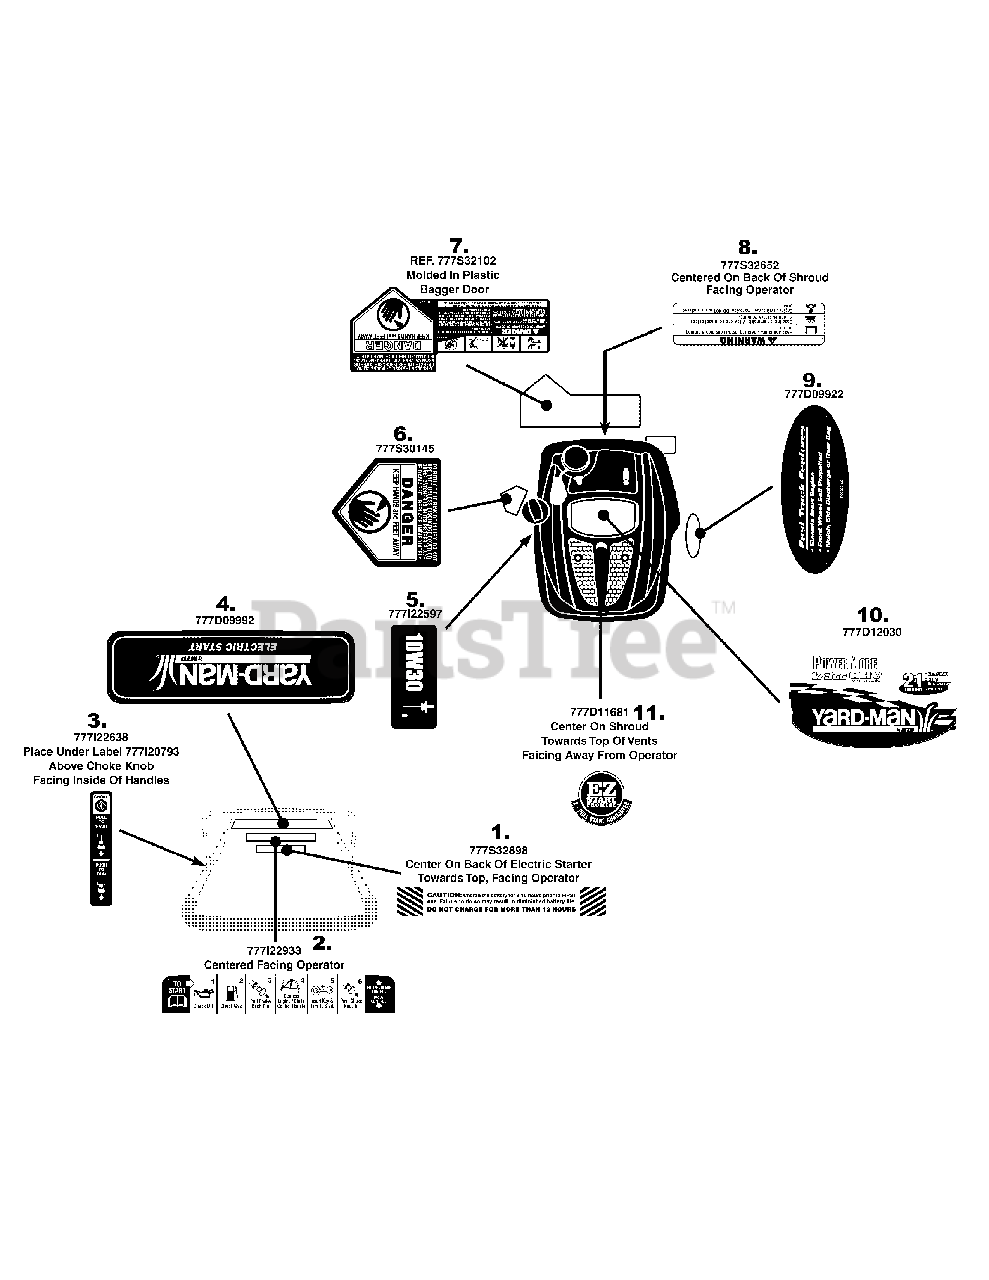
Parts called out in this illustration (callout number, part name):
1	LABEL-MOWER CHARGE CAUTION
2	LABEL-STRT INSTRUCT
3	LABEL-MOWER HANDLE:CHOKE START/RUN
4	LABEL-MOWER HANDLE YARD MAN ELEC
5	LABEL:MOWER SHROUD
6	LABEL
7	LABEL
8	LABEL:MOWER:ENGINE SHROUD
9	LABLABEL-MOWER DECK YARD MAN FAST TRKEL
10	LABEL-MOWER SHROUD YARD MAN 3 IN 1
11	LABEL-MOWER SHROUD EZ START
